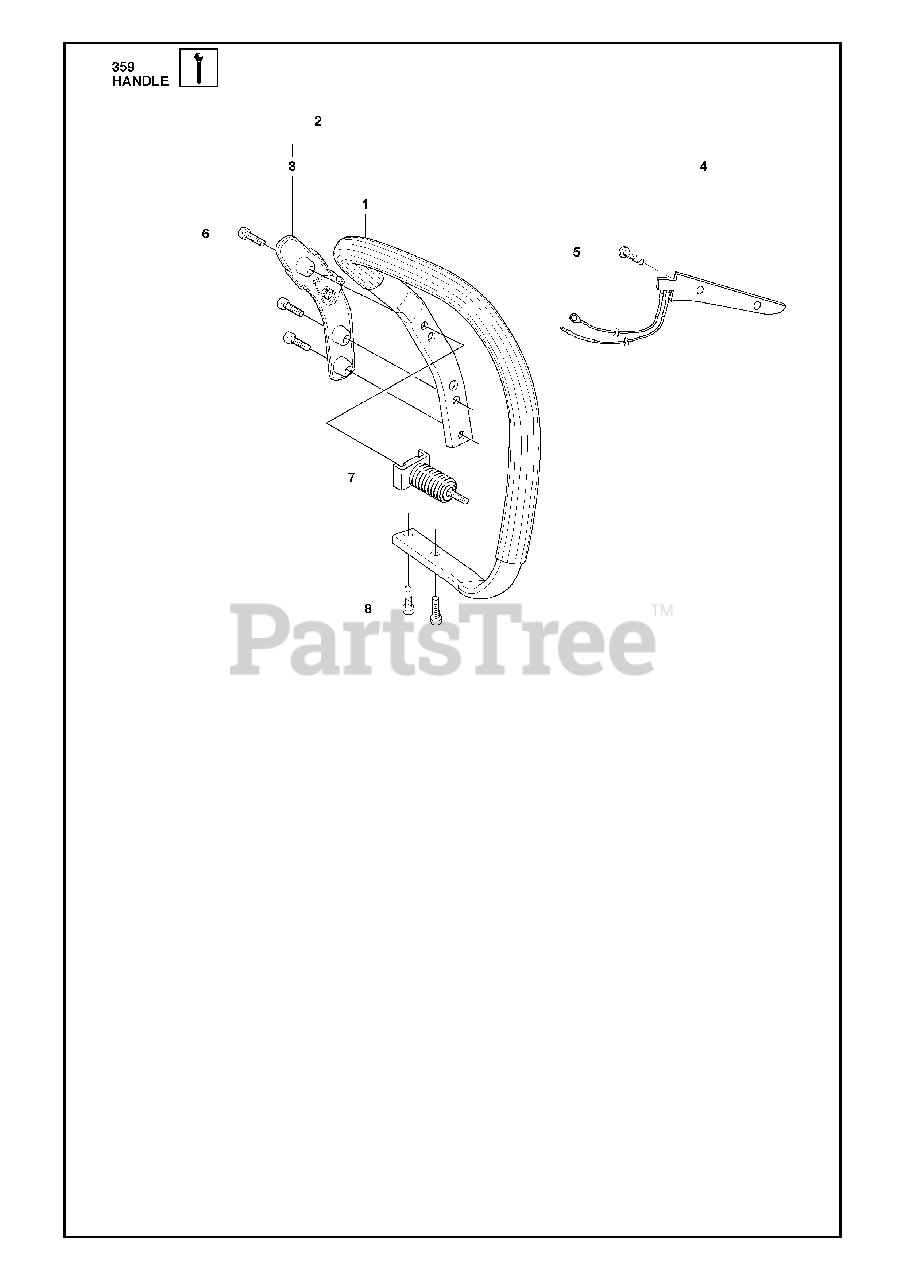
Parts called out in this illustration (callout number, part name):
1	FRONT HANDLE
2	FRONT HANDLE
3	SWITCH
4	HANDLE CIRCUIT
5	SCREW
8	SCREW IHSCFT
